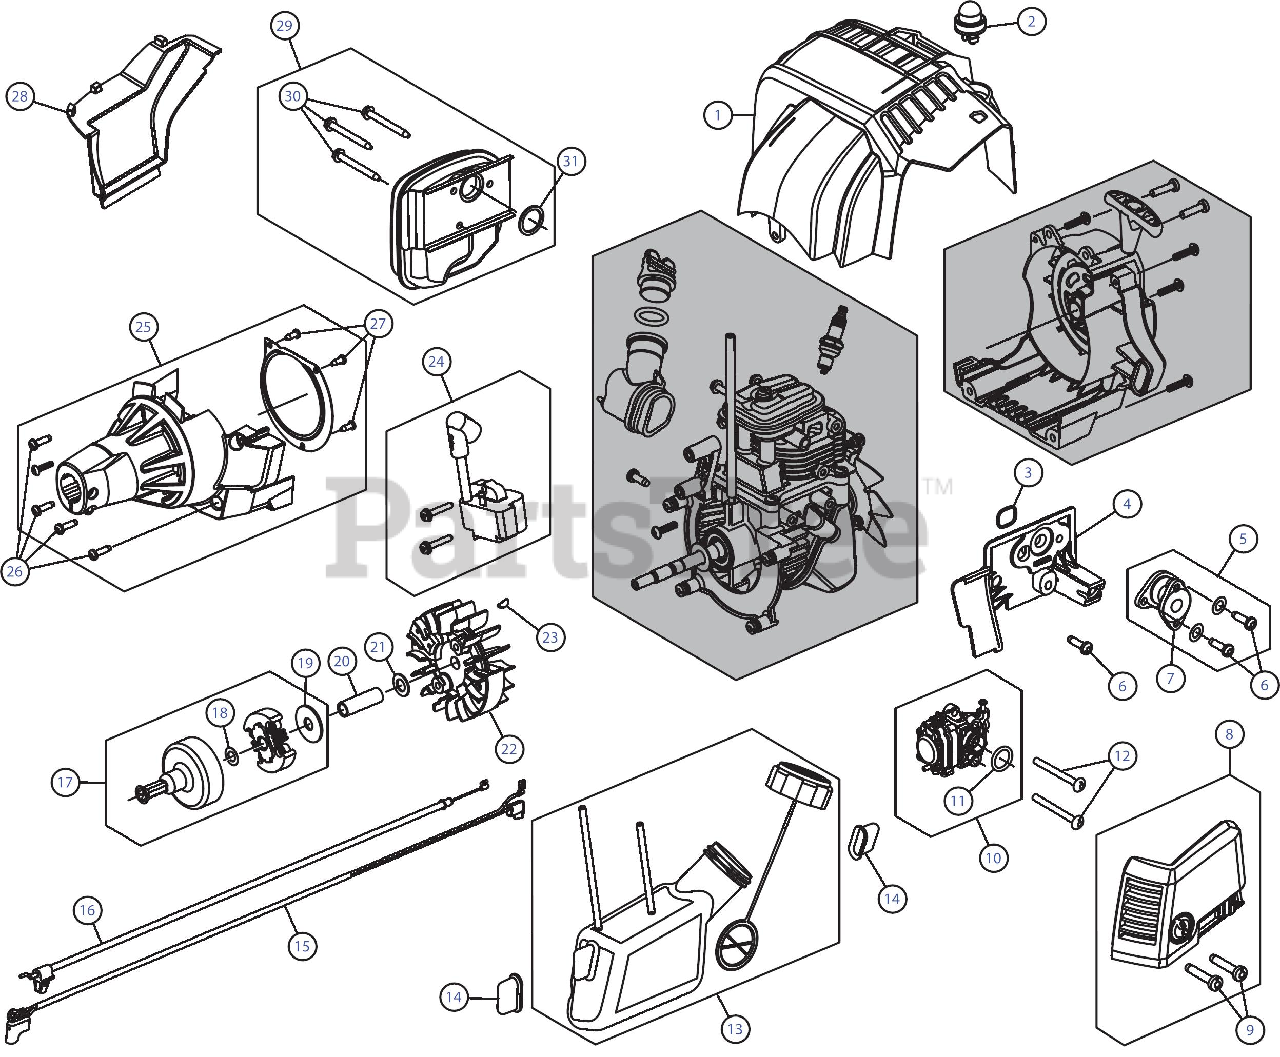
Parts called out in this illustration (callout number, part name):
1	Top Housing
2	Air Purge Primer
3	O-Ring
4	Intake Port
5	Boot Assembly (includes 6 & 7)
6	Screw
8	Air Cleaner Assembly
10	Carburetor Assembly (includes 11)
13	Fuel Tank Assembly
14	Fuel Tank Pad
15	Lead Wire
16	Throttle Cable
17	Clutch Assembly (includes 18 & 19)
18	Thrust Washer
19	Clutch Washer
20	Spacer
21	Washer
22	Flywheel
24	Module Assembly
25	Clutch Cover Assembly (includes 26 & 27)
27	Screw
28	Rear Engine Cover
29	Muffler Assembly (includes 30 & 31)
31	Muffler Gasket
